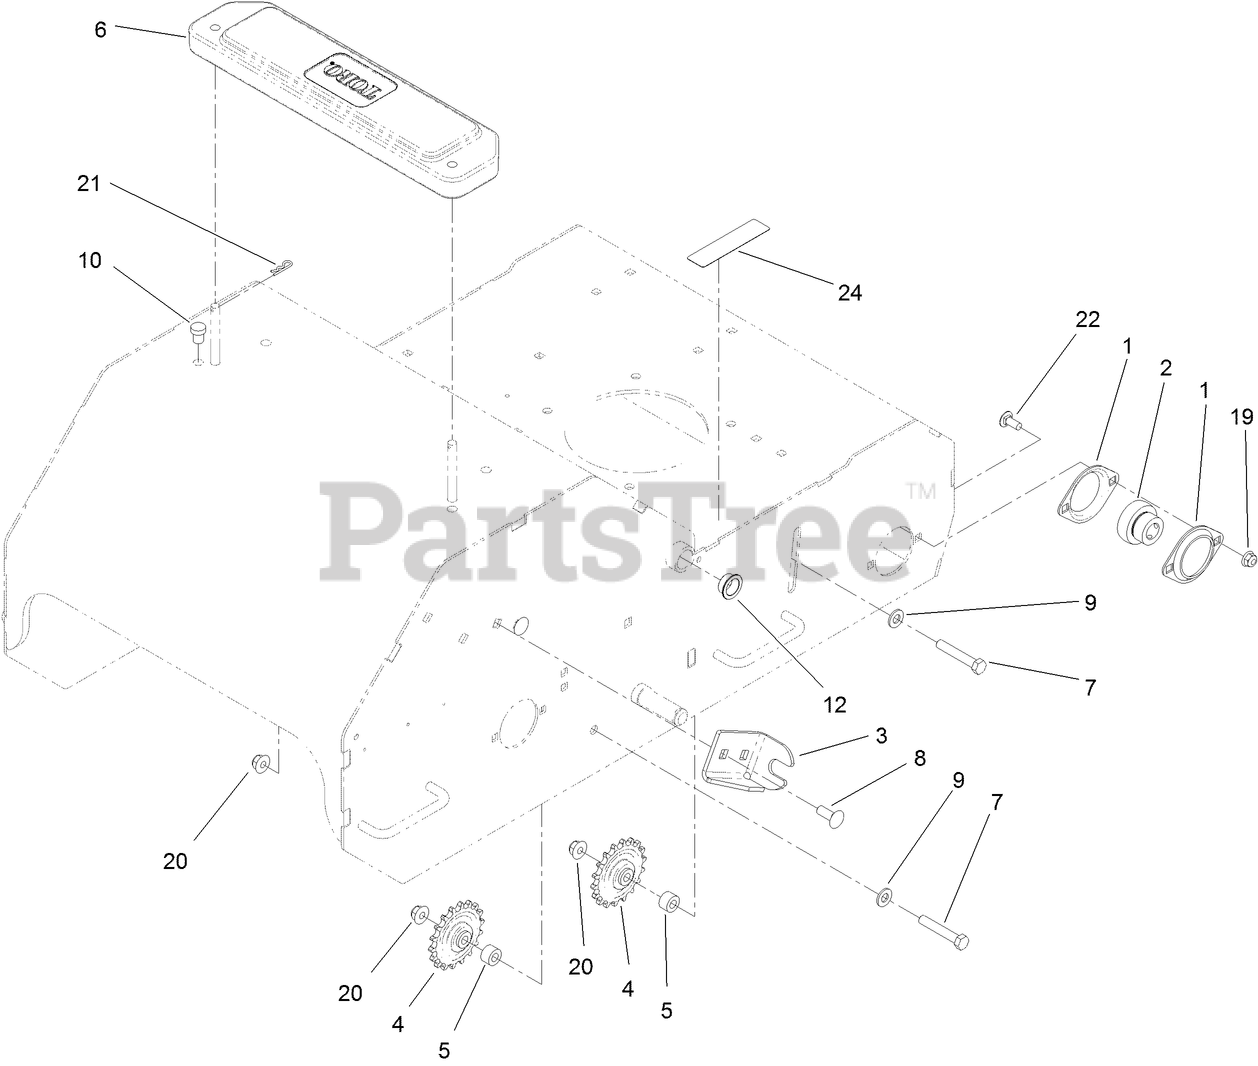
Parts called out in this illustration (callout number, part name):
1	FLANGE-BEARING
2	BEARING-LOCK, COLLAR
3	BRACKET-MOUNT, CABLE
4	SPROCKET-IDLER
5	SPACER-SPROCKET
6	WEIGHT-CAST
7	SCREW-HH
8	SCREW-CARR
9	WASHER-FLAT
10	BUMPER-RUBBER
12	BUSHING-BRONZE
19	NUT-HF, NI
20	NUT-HF, NI
21	PIN-COTTER
22	SCREW-CARR
24	DECAL-ARRESTER, SPARK
